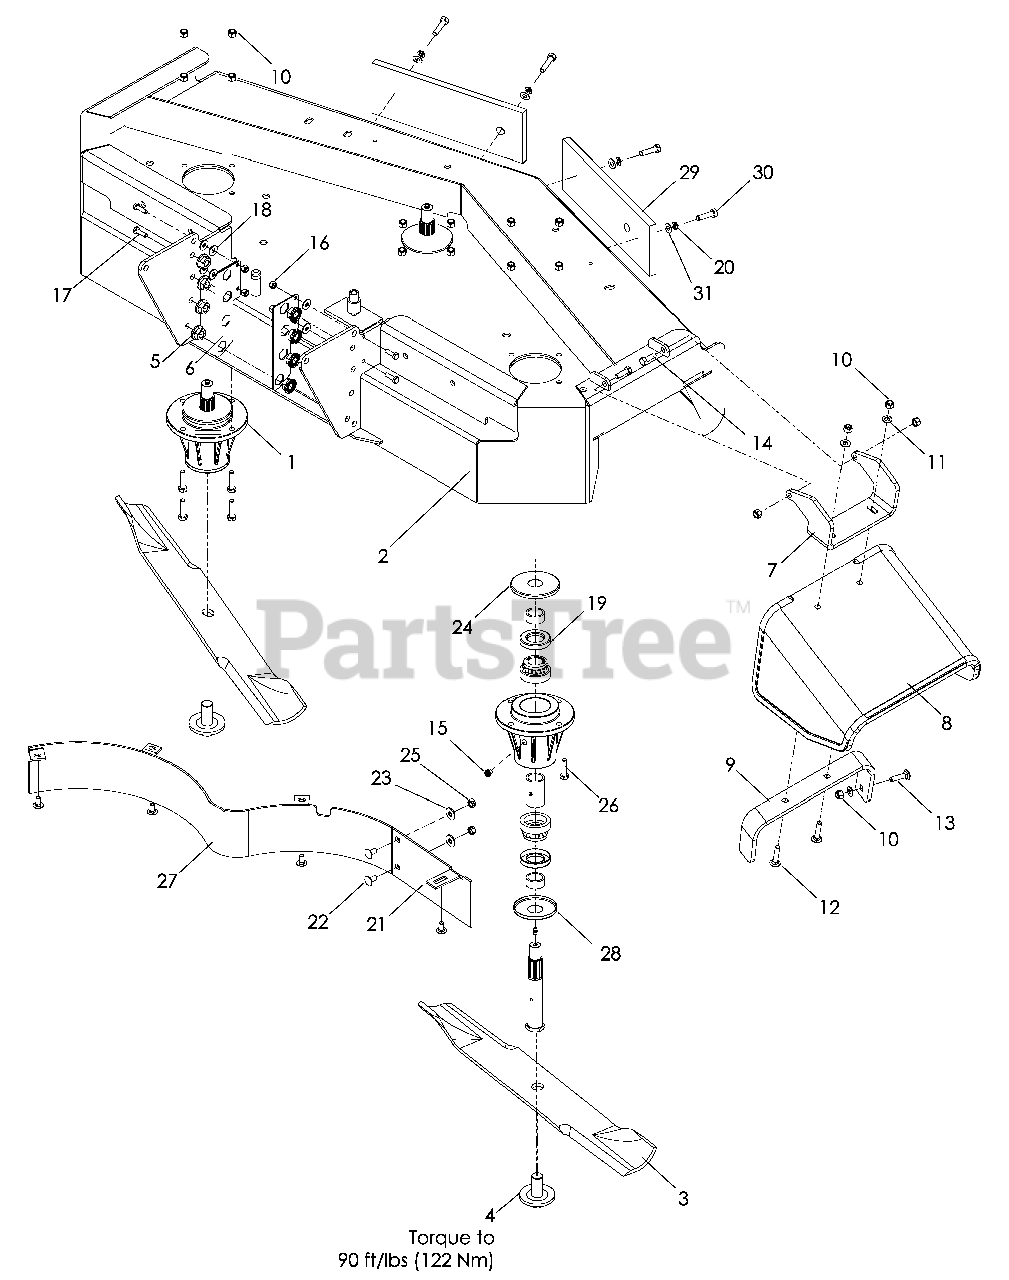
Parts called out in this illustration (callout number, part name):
1	SPINDLE ASSEM
2	DECK W DECALS, 48"
4	BOLT, BLADE
5	NUT, FLANGE, ½-13
6	NUT, PLATE
7	HINGE, CHUTE
8	RUBBER CHUTE
9	REINFORCEMENT, BRKT
10	NUT 5/16-18 HEX NYLOC
11	WASHER 5/16 SAE FLAT
12	RHSNB 5/16-18 x 1½
13	RHSNB 5/16-18 x 1¼
14	HCS 5/16-18 x 1
16	NUT ¼-20 HEX NYLOC
17	HCS ¼-20 x 7/8
18	WASHER ¼ FLAT
19	SEAL, SHAFT
20	WASHER ½ SLW
21	CENTER BAFFLE
22	RHSNB 5/16-18 x 5/8
23	WASHER 5/16 STD FLT
24	DUST CAP, TOP
25	NUT 5/16-18 HEX CTRLK
26	HCS 5/16-18 x 1¼
27	MAIN BAFFLE
28	DUST CAP, BOTTOM
29	WEIGHT, COUNTER
30	HCS ½-13 x 1½
31	WASHER ½ SAE FLAT
